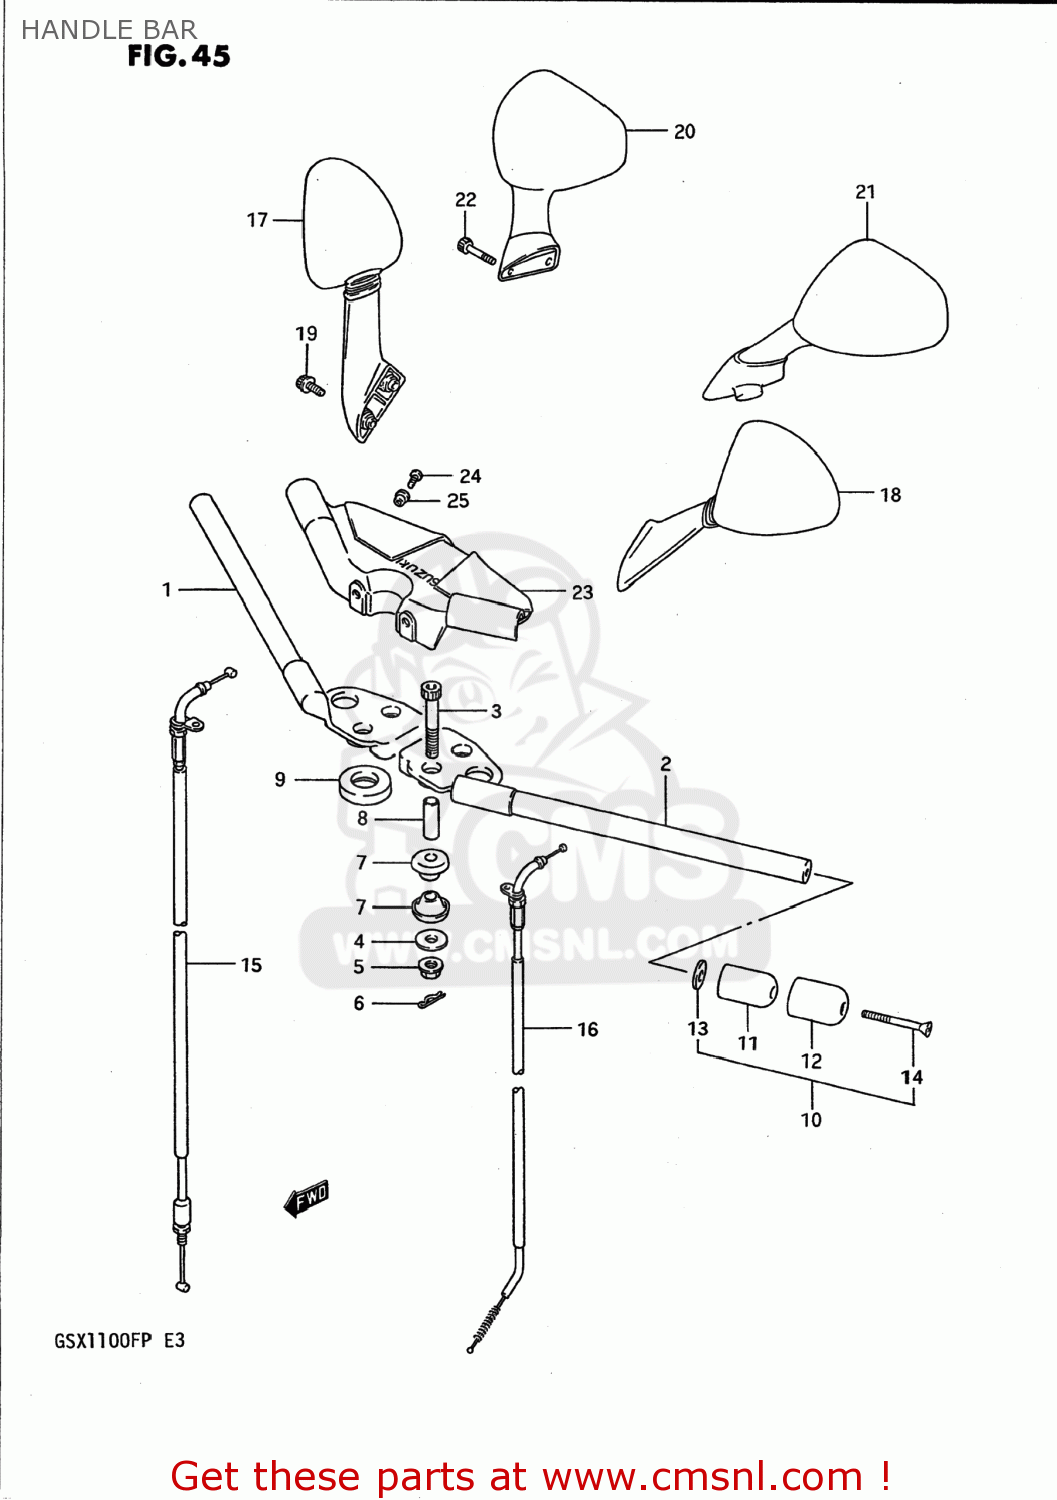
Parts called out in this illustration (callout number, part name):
1	HANDLEBAR,RIGHT
2	HANDLEBAR,L
3	BOLT L:70
4	WASHER
5	NUT 10MM
6	CLIP
7	RUBBER,HANDLE HOLDER
8	SPACER
9	CUSHION,HANDLE INNER CAP
10	BALANCER SET,HANDLEBAR
11	BALANCER,HANDLEBAR
12	CAP,BALANCER
13	SPACER,BALANCER
14	SCREW
15	CABLE ASSY,THROTTLE
16	CABLE ASSY,STARTER
17	MIRROR ASSEMBLY,REAR VIEW
18	MIRROR ASSEMBLY,REAR VIEW,LEFT
19	PLUG ,6X20
20	MIRROR ASSY,RR VIEW,R
21	MIRROR ASSY,RR VIEW,L
22	PLUG ,6X20
23	COVER,HANDLE
24	SCREW, FRONT & REAR
25	WASHER
